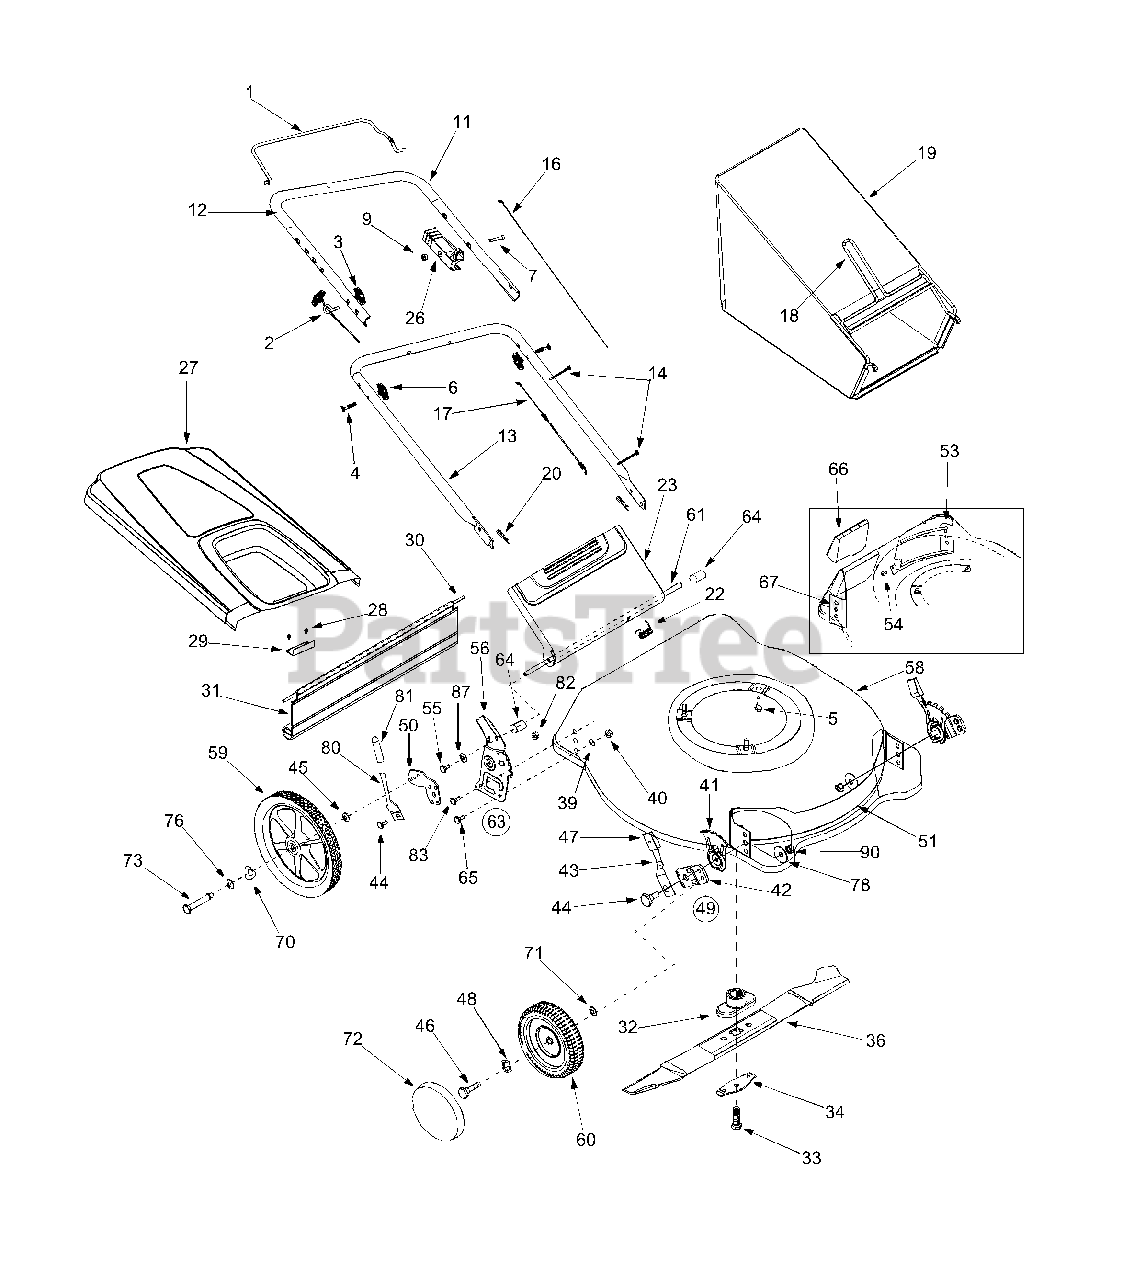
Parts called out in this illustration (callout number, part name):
2	Rope Guide
3	Handle Knob
4	Carriage Bolt 5/16-18 x 2"
5	Hex Washer Screw 3/8-16 x 1.00"
6	Hand Knob
7	C-Sunk Screw 1/4-20 x 1.3"
9	Hex Lock Nut 1/4-20
14	Cable Tie
16	Blade Control Cable - 39"
17	Throttle Cable - 51"
19	Grass Catcher Bag w/o Logo
20	Hairpin Clip
22	Door Spring
27	Hard Top w/ Logo
28	Hex Washer Screw 1/4-20 x .625
31	Rear Flap
32	Blade Adapter
33	Hex Bolt 3/8-24 x 1.5
34	Blade Bell Support
36	21" Mulching Blade
39	Bell Washer .39 I.D. x 1.38 I.D.
40	Hex Nut 3/8-16
41	Height Adj. Plate
43	Front Wheel Spring Lever
44	Shoulder Bolt .5" x .357"
45	Bell Wash. .38" I.D. x .88" O.D.
46	Front Axle Bolt
47	Height Adjuster Knob
48	Wave Washer .510 x .750
49	Height Adjuster Assembly - R.H.
50	Pivot Bar - R.H.
54	Tap Screw 1/4-14 x .625.
55	Hew Washer Screw 1/4-20 x .500
60	Front Wheel Assembly 8 x 2
61	Chute Door Pivot Rod
63	Handle Bracket Assembly. - R.H.
64	Spacer .375 O.D. x .50 I.D. x 1.02"
65	Hex Cap Screw 3/8-16 x .75
66	Rear Mulch Plug
70	Wave Washer
71	Spring Washer
72	Hub Cap
73	Rear Axle Bolt
76	Flat Washer
78	Bell Washer
80	Spring Lever, Rear
81	Foam Grip
82	Hex Flange Lock Nut 3/8-16
83	Hex Washer Screw 1/4-14 x .625
87	Bell Washer .265 x .75 x .062
90	Hex Nut 3/8-16
